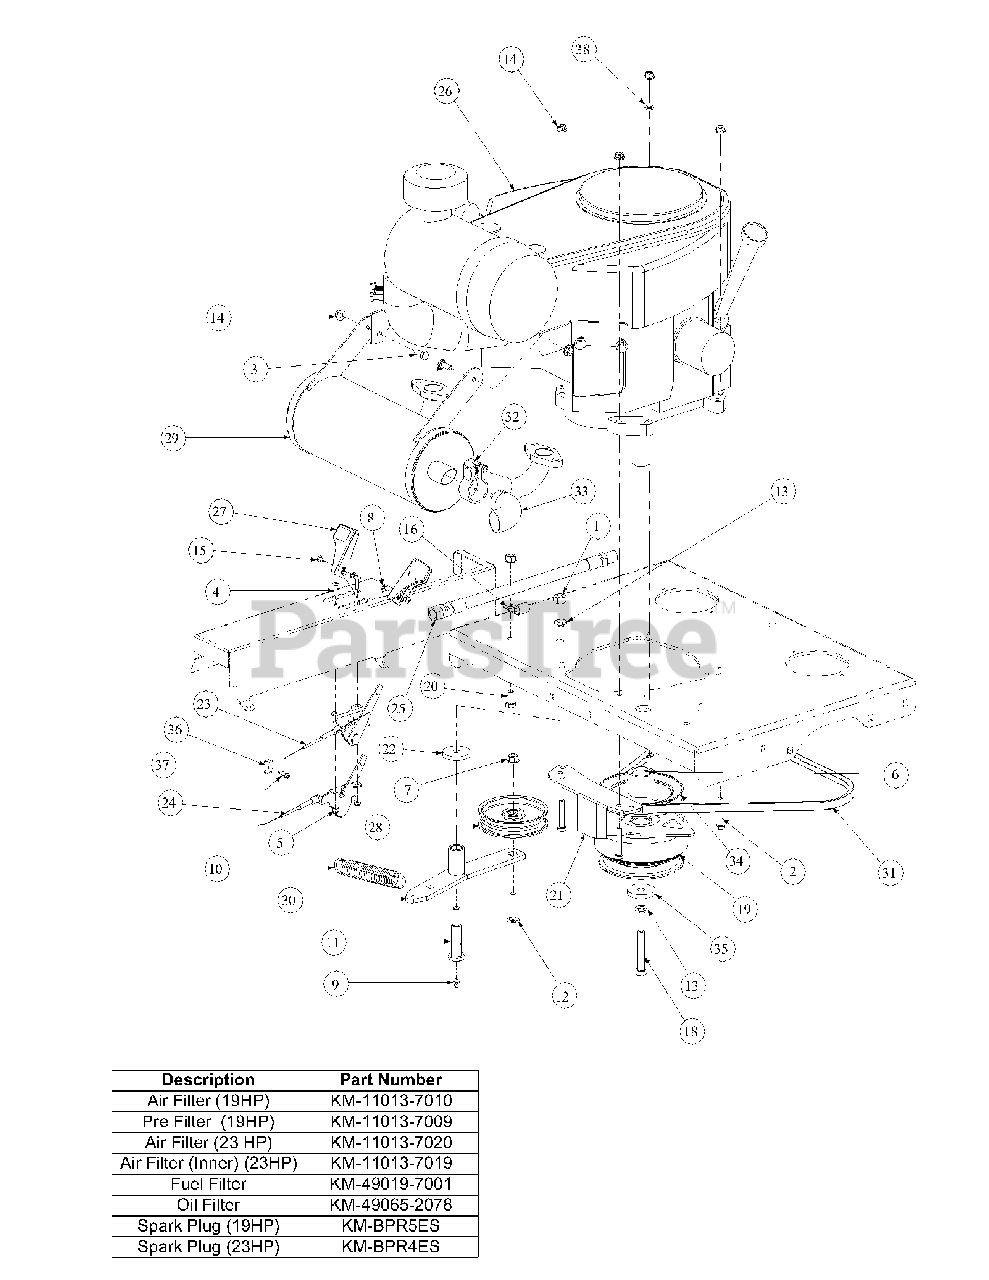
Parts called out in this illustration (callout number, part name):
1	Hex Nut, 7/16-14
2	HHCS, 5/16-18, 1-3/4
3	Hex Cap Screw, 5/16-18 x 3/4
4	Round Hd. Machine Screw, 10-32 x 3/4
5	Lock Nut, Nylon Insert, 10-32
6	Key, 1/4 x 1/4 x 3
7	Flange Lock, Hex Nut, 3/8-16
8	Nut Washer, W/Star, 8-32
9	Grease Fitting, 1/4-28 x 3/16
10	Extension Spring, 1.0 OD x 5.125
11	Shoulder Screw, 7/16-14
12	Hex Carriage Screw, 3/8-16, 1.75
13	Lock Washer, 7/16
14	Hexflange Lock Nut, 5/16-18
15	Machine Screw, 8-32, .375
16	Clip, Heat Shield Cable
17	Hex Cap Screw, 1.25 x 20mm
18	Capscrew, 7/16-20 x 2.50
19	Clutch Brake, 1.125 ID
20	Hex Cap Screw, 3/8-16, .750
21	Retainer Clutch Assembly, Ogura
22	Flat Washer, 7/16 ID x 1.75 OD x .25
23	Choke, Control Cable, 43.0
24	Throttle, Control Cable, 39.0
25	Oil Drain Hose
26	23HP Kawasaki Engine
27	Control Throttle Knob
28	Flat Pulley with Flanges
29	Muffler Accessory, Kawasaki
30	Engine Idler Arm Assembly
30	Bearing
31	V Belt, A Section x .47.3
32	Tube Clamp, 1.375
33	Muffler Accessory Exhaust Tube
34	Pump Drive Pulley
35	Flat Washer, 7/16 ID x 1.75 OD x .25
36	Bolt, M5 x 18
37	Choke Cable Clamp
38	Flat Washer, .320 ID x .591 OD x .078
